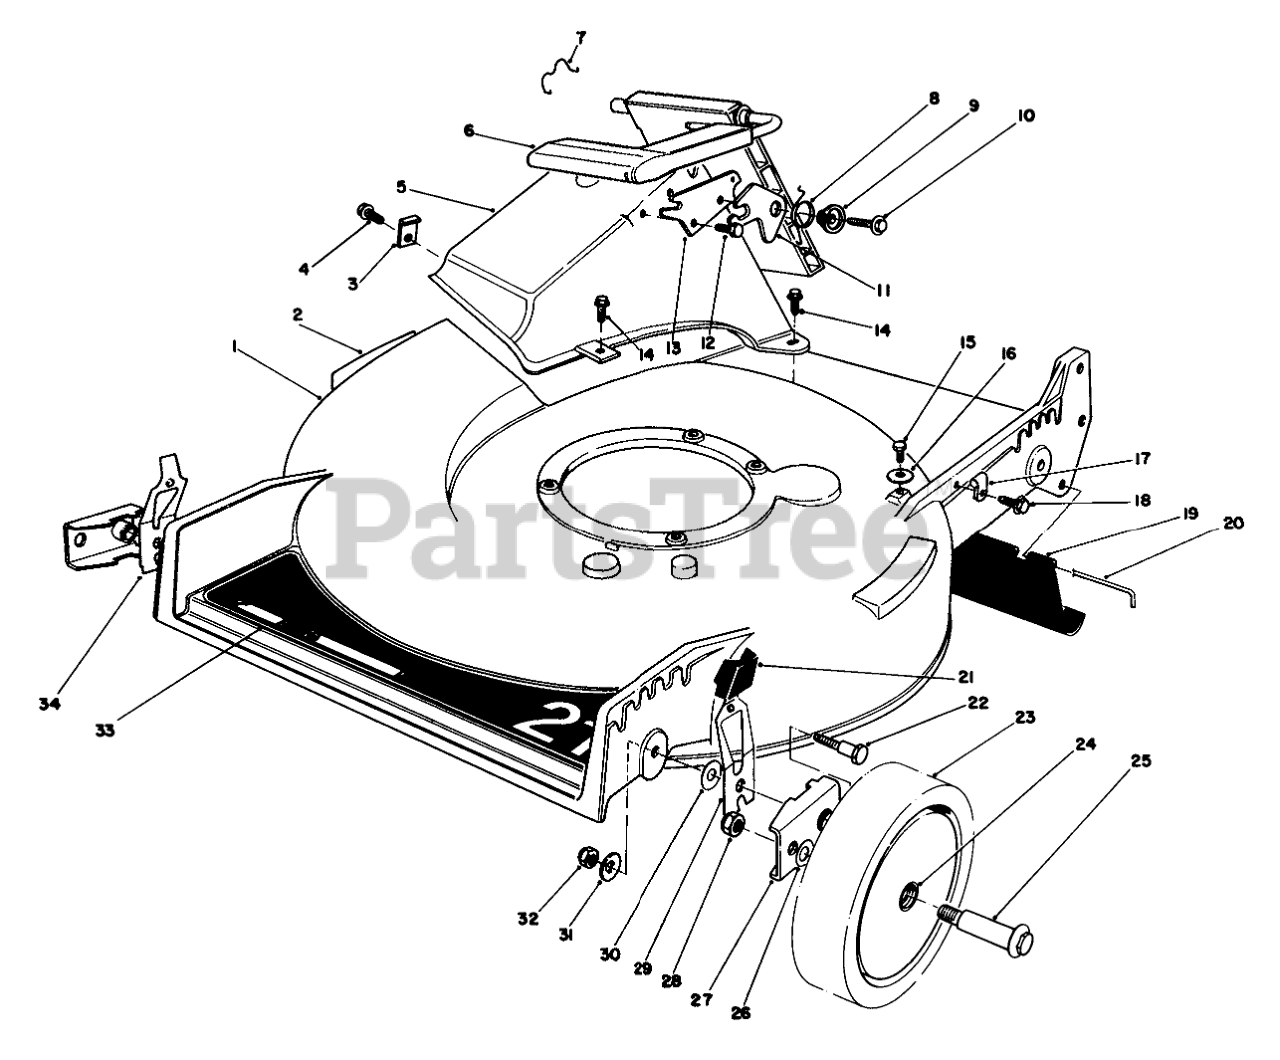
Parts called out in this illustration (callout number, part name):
1	Housing (Incl. Ref. #2)
2	DECAL-DANGER
3	TUNNEL CLIP
4	SCREW
5	Tunnel Discharge
6	Discharge Door Assembly
7	DOOR RET SPRING
8	TORSION SPRING
9	DOOR SPACER
10	SCREW-HWH
11	SAFETY LATCH
12	SCREW-PLASTITE
13	DOOR LATCH PLATE
14	SCREW-HWH
15	SCREW-HWHTF
16	WASHER-FLAT
16	CLAMP-CABLE
17	CLAMP-CABLE
18	SCREW
19	SHIELD-TRAILING
20	ROD-SHIELD
21	KNOB-ARM
22	PIVOT SCREW
23	Wheel & Tire Assembly (Incl. Ref. #24)
24	BUSHING
25	BOLT-WHEEL
26	WASHER
27	HP PIVOT ARM ASM
28	Nut
29	L. HP SPRING ARM ASM
30	WASHER-PIVOT
31	WASHER-BELLEVILLE
32	NUT-LOCK, NI
33	DECK DECAL
34	R HP SPRING ARM ASM
